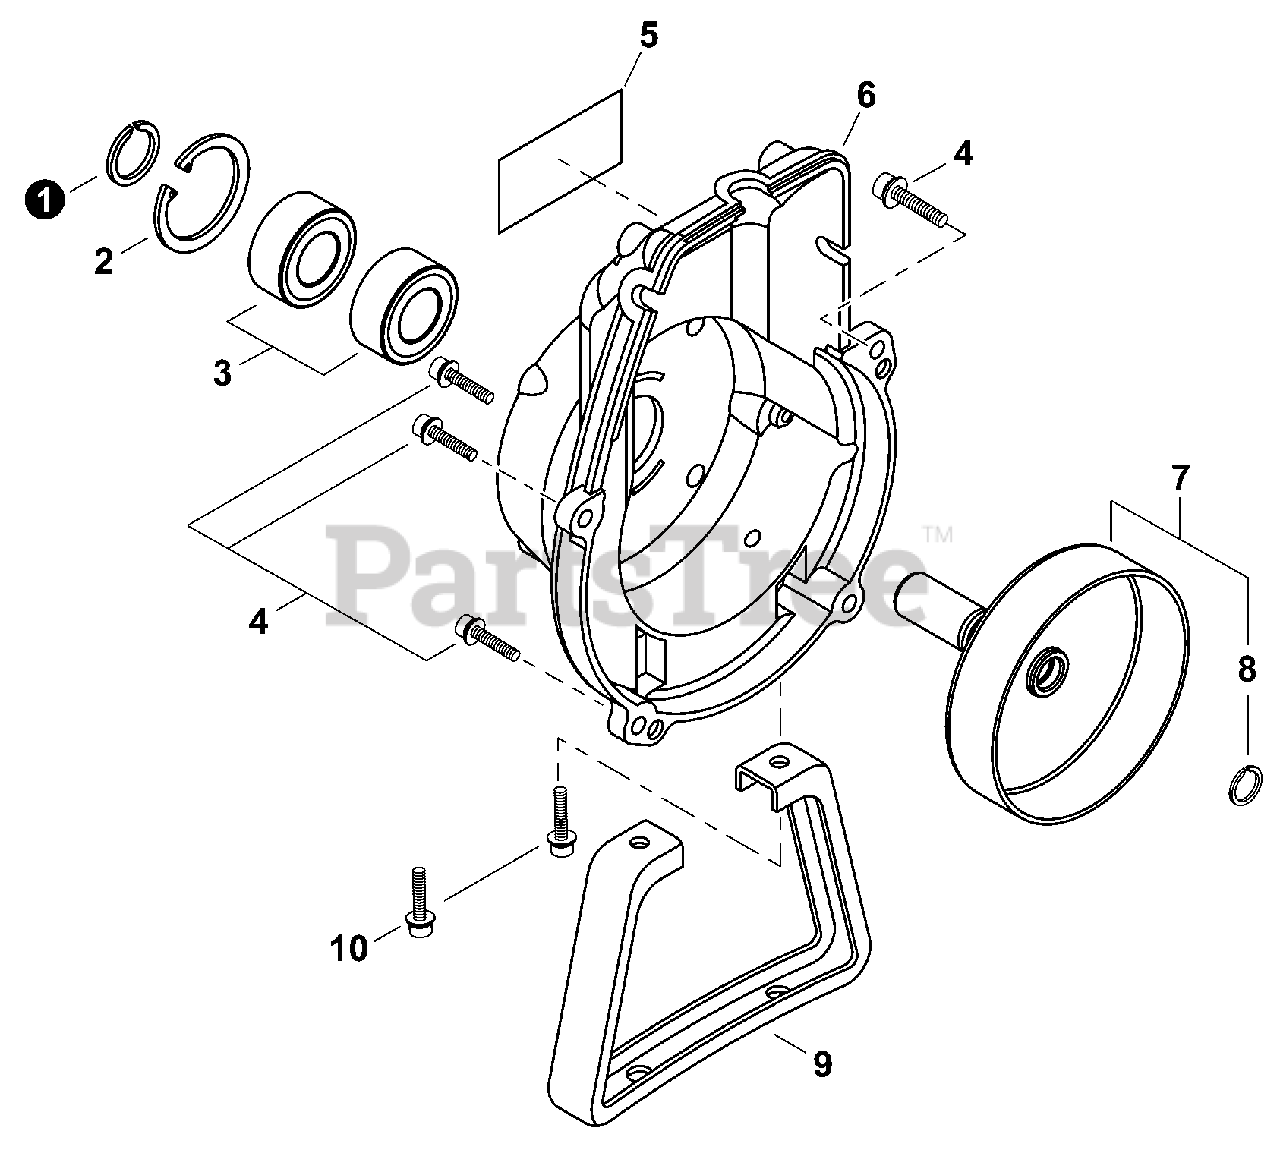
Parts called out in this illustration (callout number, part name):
1	RING, SNAP
2	RING, SNAP Ø32
3	BEARING, BALL 6002 DDU
4	BOLT M5×20
5	LABEL, TRADE
6	COVER, FAN
7	DRUM ASSY, CLUTCH
8	RING, SNAP Ø11.4
10	BOLT M5×16
